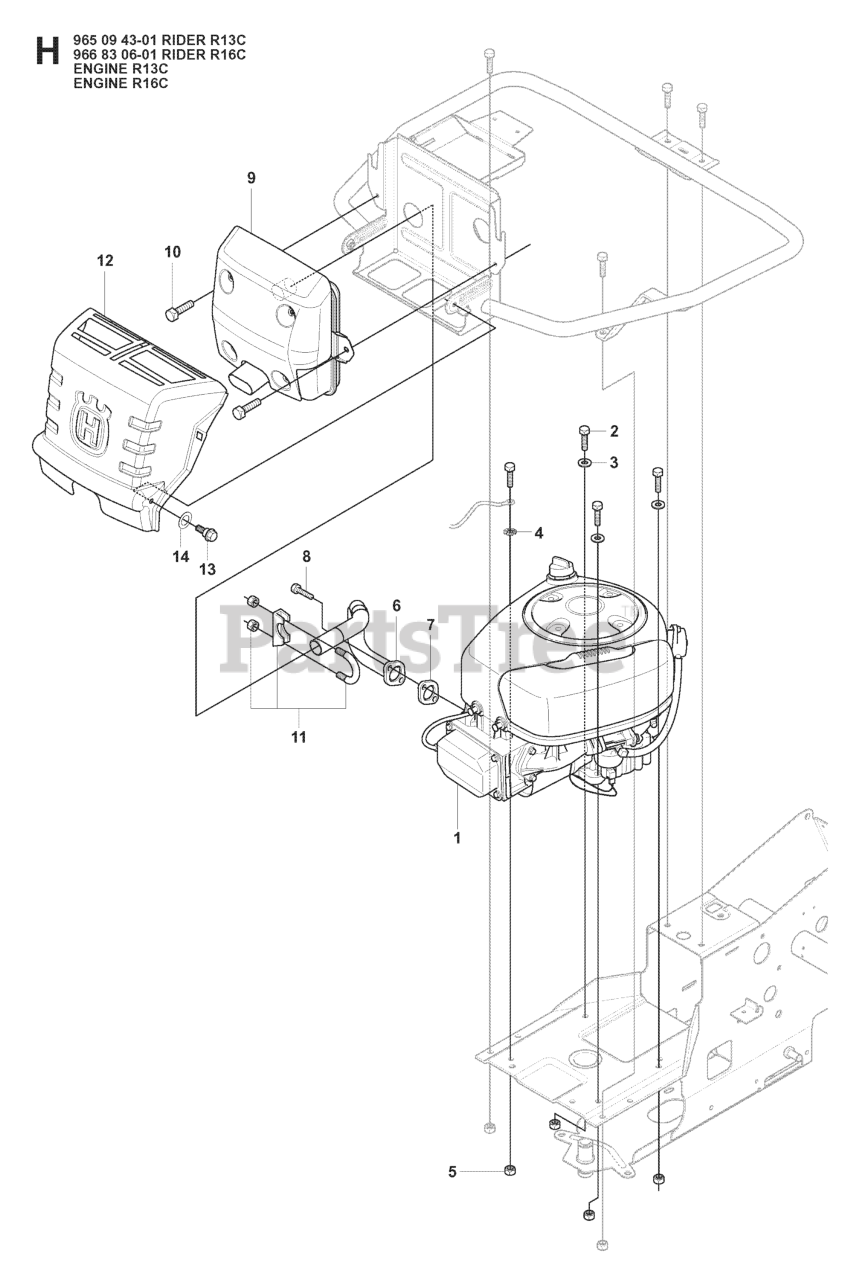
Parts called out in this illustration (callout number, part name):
3	WASHER BRB 8.4X17
5	LOCKNUT M8
6	EXHAUST PIPE ASSY
9	MUFFLER ASSY
11	CLAMP
12	HEAT PROTECTOR
14	SPRINGWASHER
